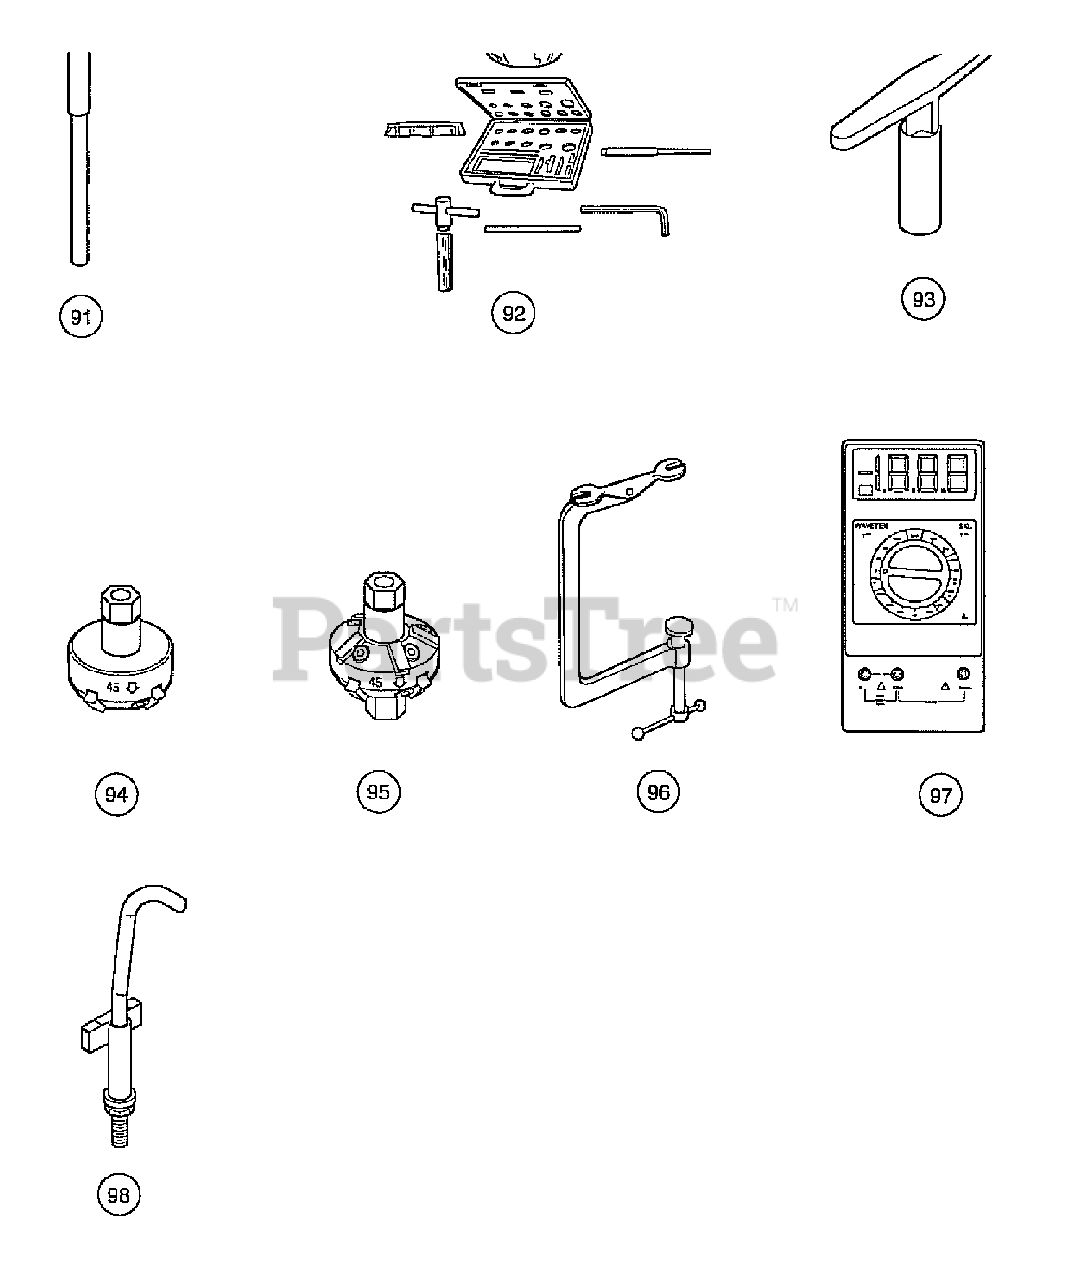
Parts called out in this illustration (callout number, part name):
91	Valve Seat Cutter Guide
92	Valve Seat Cutter Set
93	Valve Seat Cutter T-Wrench
94	Valve Seat Cutter, 45° (32 mm diameter)
95	Valve Seat Cutter, 45°/30° (35 mm diameter)
96	Valve Spring Compressor
97	Volt Ohm Meter
98	Tool, Tensioning, Starter Generator
